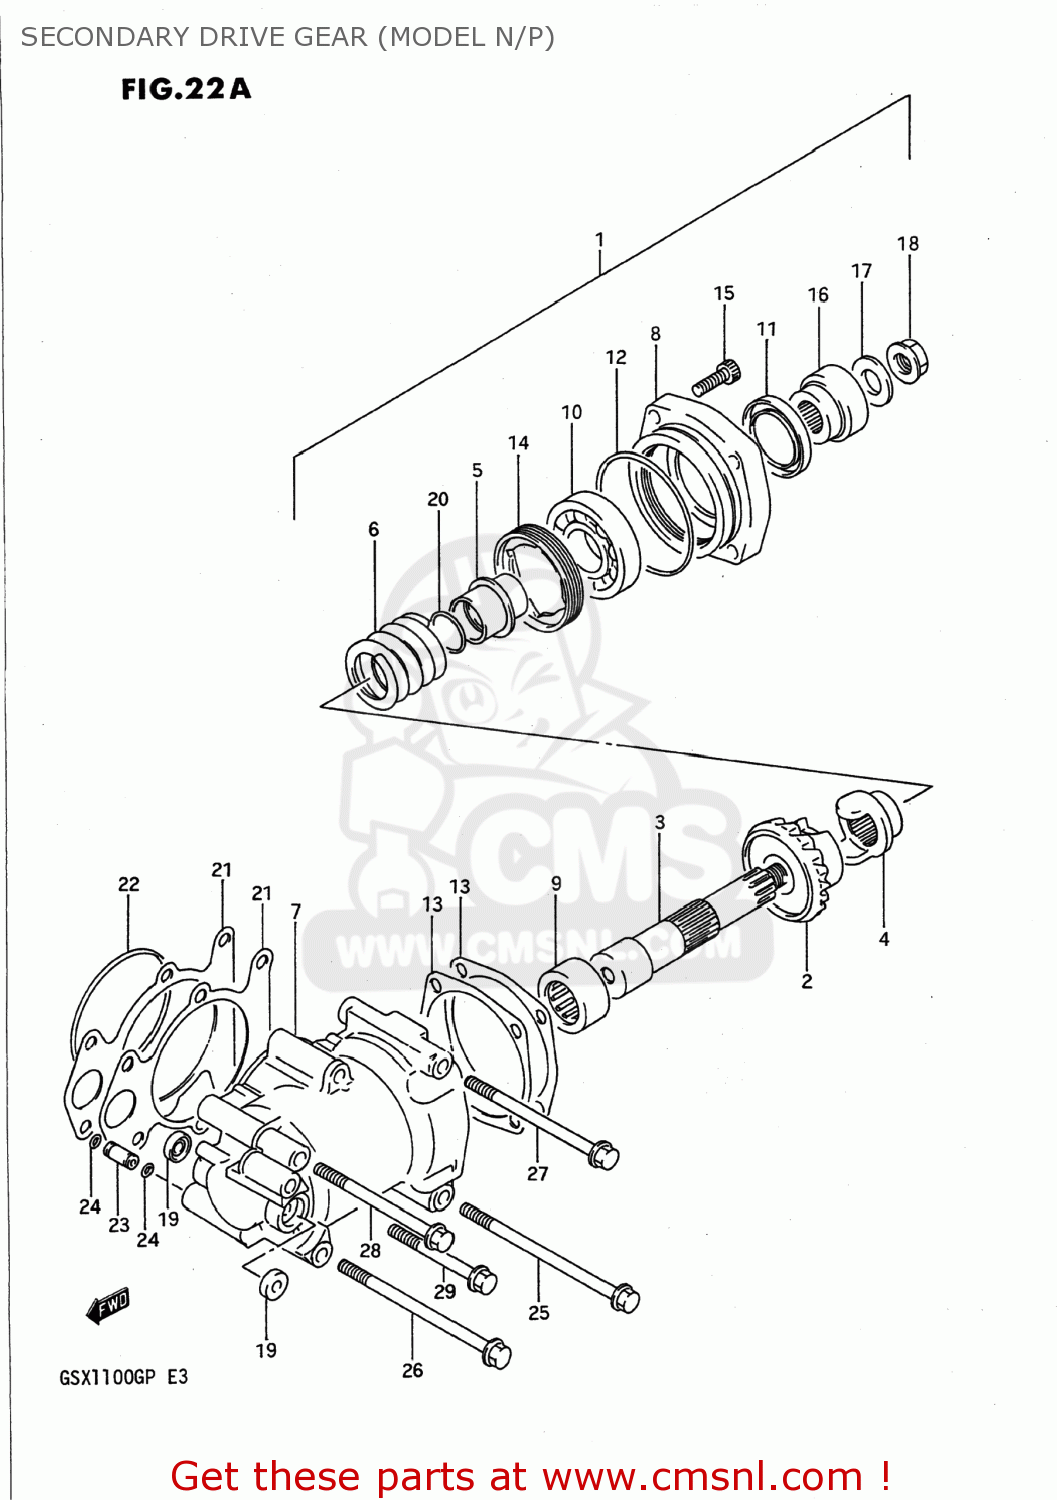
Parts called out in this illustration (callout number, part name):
1	GEAR & CASE SET,SECONDARY BEVEL
2	GEAR,SECONDARY DRIVEN
3	SHAFT,SECONDARY DRIVEN BEVEL
4	DOG,OUTPUT CAM
5	STOPPER,CAM SPRING
6	SPRING
7	CASE COMP,SECONDARY GEAR
8	HOUSING,SECONDARY DRIVEN BEARING
9	BEARING(32X48X22)
10	BEARING(28X68X18)
11	SEAL,OIL(38X54X6)
12	O RING(D:3.7,ID:76.5)
13	SHIM,SECONDARY DRIVEN
14	STOPPER,SEC DRIVEN BEARING
15	BOLT
16	COUPLING,SECONDARY DRIVEN BELT
17	WASHER(16.5X36X4)
18	NUT
19	SEAL,OIL(6X18X5)
20	O RING(D:2,ID:21.9)
21	SHIM,SECONDARY DRIVE NO.1
22	O RING(D:2.2,ID:88)
23	PIPE,SECONDARY CASE OIL
24	O RING(D:1.7,ID:6)
25	BOLT(8X125)
26	BOLT(8X120)
27	BOLT(8X105)
28	BOLT (8X95)
29	BOLT (8X70)
